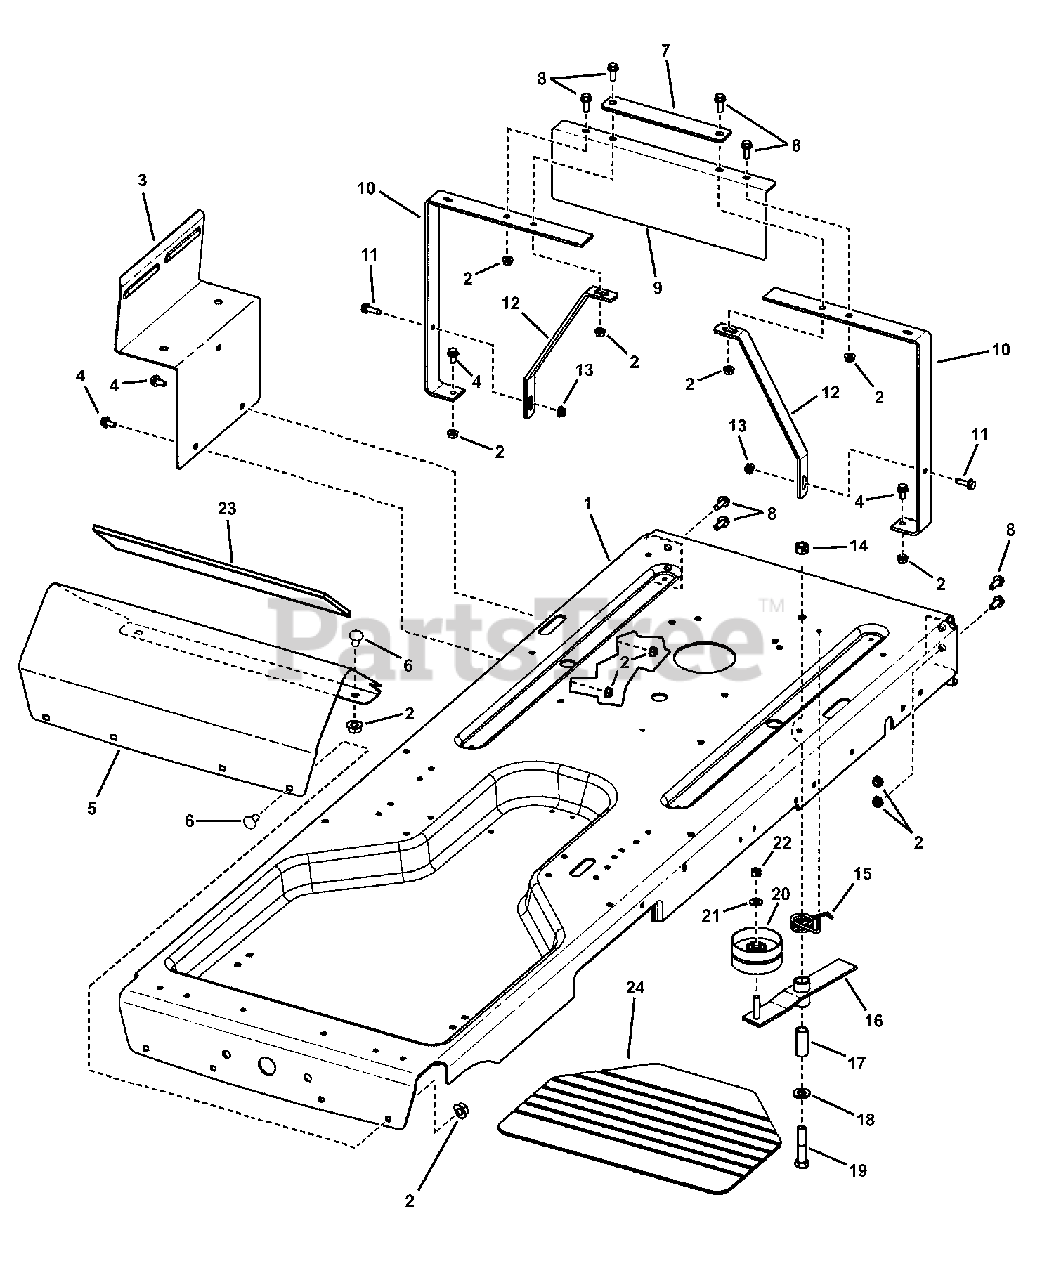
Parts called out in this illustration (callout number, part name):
1	FRAME, RZT (Cardinal Red)
2	NUT, 5/16-18 Hex Flange Lock, GR 5
3	TANK BRACKET
4	BOLT, 5/16-18 x 5/8" Hex Flange Lock, GR 5
5	FOOTREST, Snapper (Cardinal Red)
6	BOLT, 5/16-18 x 3/4" Short Neck Carriage, GR 5
7	PLATE, Rear Seat Guard
8	BOLT, 5/16-18 x 7/8" Hex Flange Lock, YZ
9	HEAT SHIELD
10	BRACKET, Body Support
11	SCREW, 5/16-18 x 1" Hex Washer Self-Tap, GR 5
12	BRACE, Hood/Fender
13	NUT, 5/16-18 Hex Flange Lock, GR 5
14	NUT, 1/2-13 Hex Center Lock, GR 5, YZ
15	SPRING, Torsion, RH Wind
16	WELDMENT, Hydro Idler
17	SPACER, Hydro Idler
18	WASHER, .531 x 1.062 x .121 Flat, YZ
19	SCREW 1/2-13 x 2-1/2" Hex Head Cap, GR 5 (Black Phosphate)
20	IDLER, 3.25" OD x .391 ID x 1.63 Backside
21	WASHER, 3/8" Flat SAE
22	NUT, 3/8-16 Hex Center Lock, GR 5 or B, YZ
23	MAT, Foot Rest RZT
24	MAT, Floor Pan
